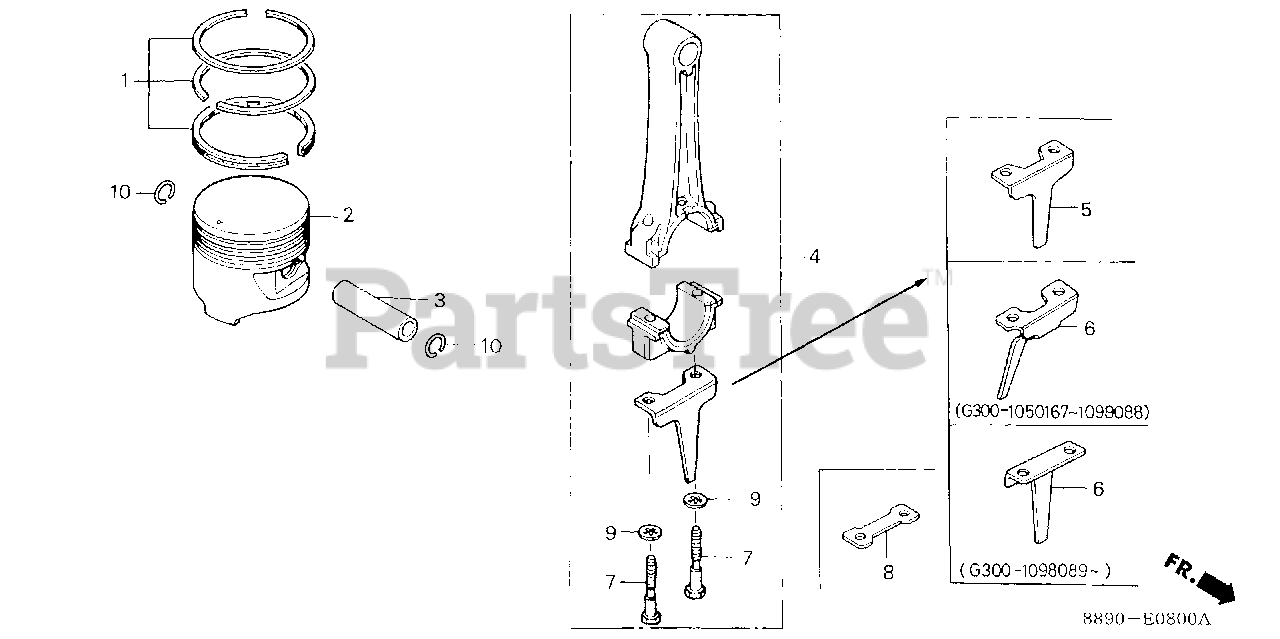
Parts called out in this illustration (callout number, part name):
1	RING SET, PISTON (STD)
1	RING SET, PISTON (0.25)
1	RING SET, PISTON (0.50)
1	RING SET, PISTON (0.50) (TEIKOKU)
1	RING SET, PISTON (0.75)
2	PISTON (STD)
2	PISTON (0.25)
2	PISTON (0.50)
2	PISTON (0.75)
3	PIN, PISTON
4	ROD ASSY., CONNECTING
4	ROD ASSY., CONNECTING (UNDER SIZE)
6	DIPPER, CONNECTING ROD
7	BOLT, CONNECTING ROD (7MM)
9	WASHER, LOCK (7MM)
10	CLIP, PISTON PIN (16MM)
